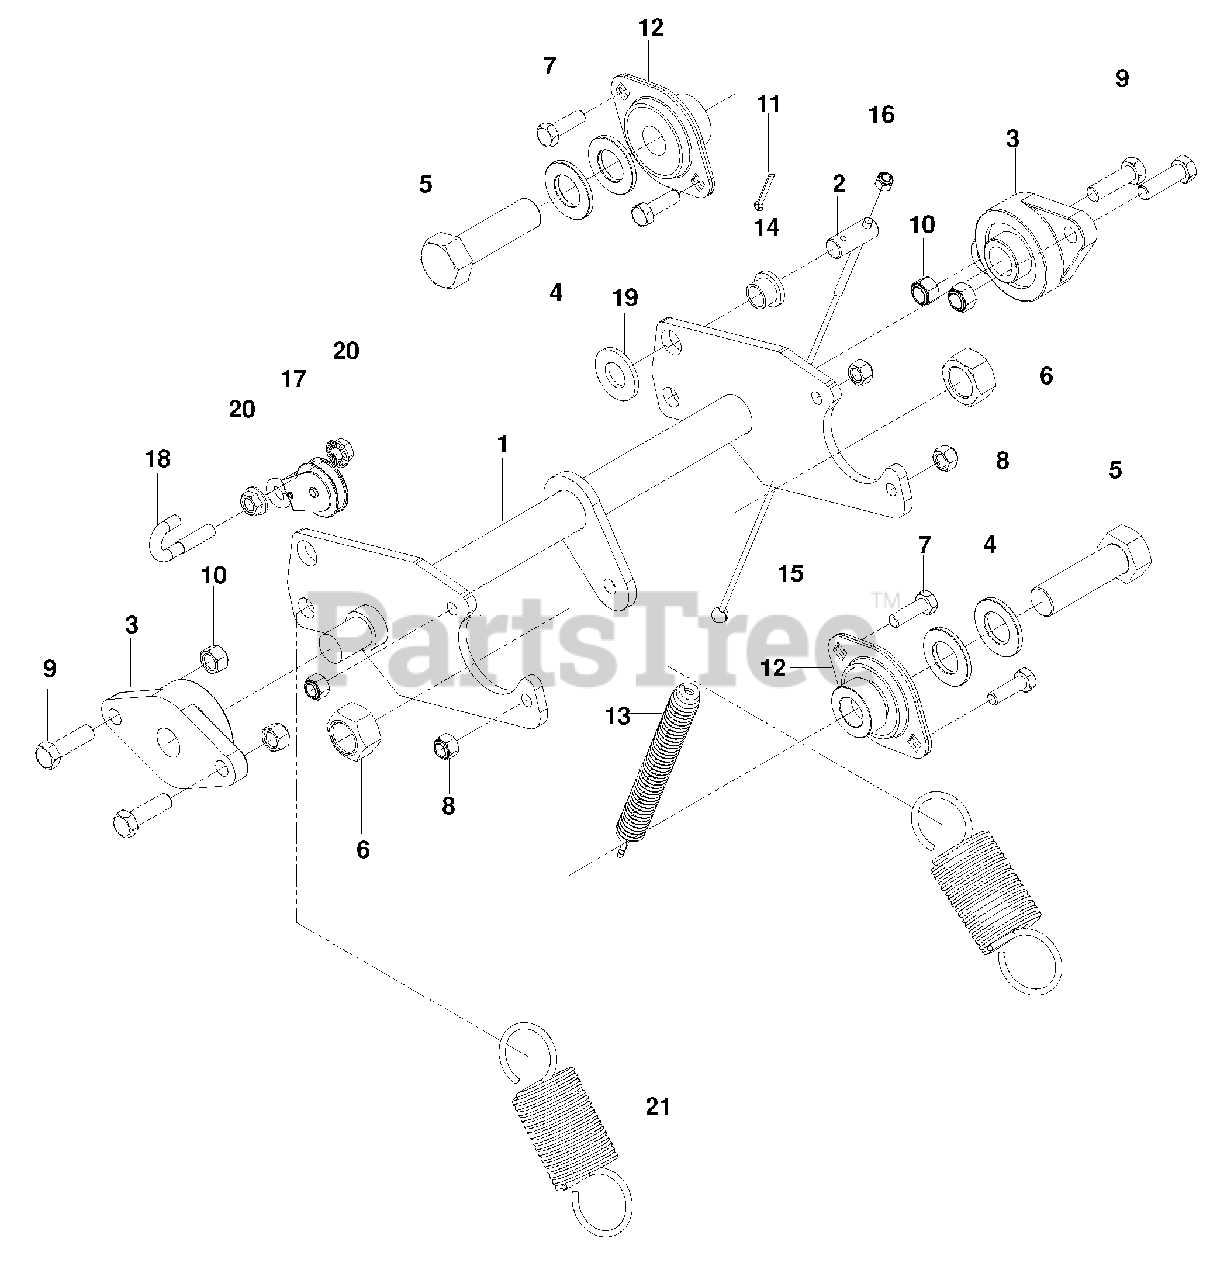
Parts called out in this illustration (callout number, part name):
2	PIN, CABLE PIVOT
3	BEARING 3/4 2 BOLT
4	WASHER 3/4 SAE
5	HCS 3/4-16 x 2 1/2
6	NUT 3/4-16 TOP LK
7	HCS 5/16-18 x 1
8	NUT 5/16-18 NYLOC
9	HCS 3/8-16 x 1 1/4
10	NUT 3/8-16 NYLOC
11	PIN COTTER 1/8 x 1
12	FLANGE 3/4
13	SPRING EXTENSION
14	BUSHING, FLANGED
15	CABLE, PULL
16	NUT 1/4-20 NYLOC
17	PULLEY BRACKET
19	WASHER 5/8 SAE
20	NUT 5/16-18 WHIZLK
21	SPRING, EXTENSION
